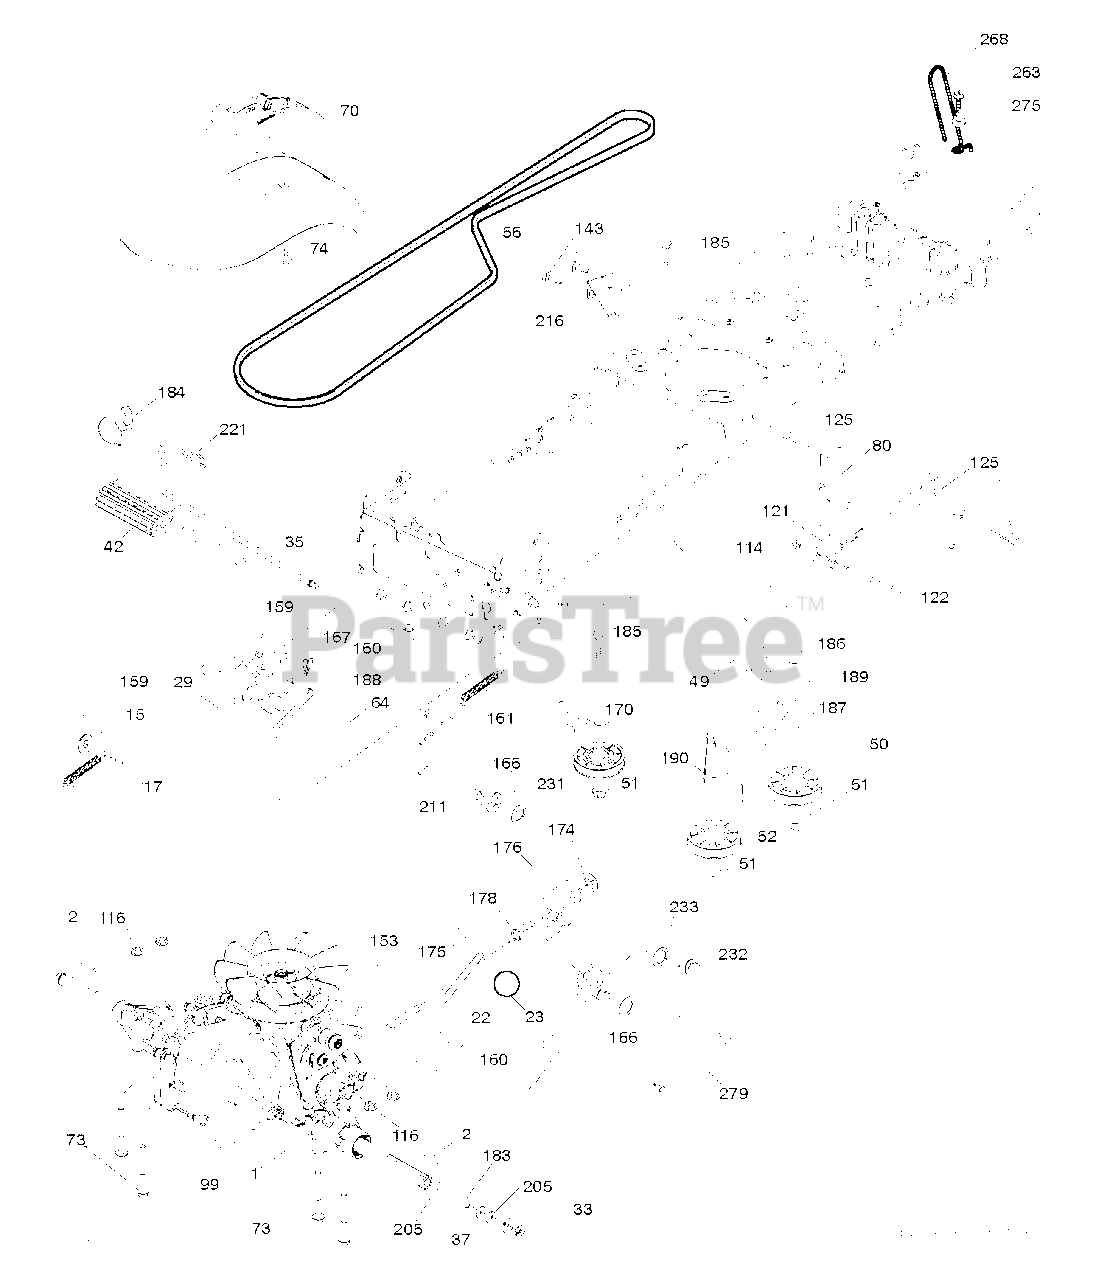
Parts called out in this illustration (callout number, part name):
2	SQUARE KEY
17	SPRING.BRAKE.HG3000/3500
22	ROD.SHIFT.FENDER.TLT.2006
23	KNOB.DUCKHEAD.1/2
29	ROD.BRAKE.T2.TEX
33	E-RING LT
35	ROD, BRAKE, PARK
42	PEDAL COVER T
49	BOLT
50	IDLER.FLAT.910.OFFSET
51	NUT LOCK FLG 3/8-16 UNC
52	IDLER.V-GROOVE.910.OFFSET
56	Ground Drive Belt, T2 HP CE
64	SHAFT.ASM.PEDAL.BRAKE.
70	CONSOLE.SHIFT.STL.HYD.BLACK
73	BOLT HEX 5/16-18 GR 5
74	SCREW.HI-LO.CONSOLE
80	Strap.Torque.T2
99	ROD.ASM.BYPASS.SPRING.T2.FS
114	NUT.71038.31-18.HEX.NYLOCK
116	NUT LOCK HEX FLANGE 5/16-18
121	BRACKET STRAP TORQUE
122	BOLT.5/16-18X2.5
125	SCREW
153	RETAINER M
159	COTTER PIN
160	RETAINER CLIP
161	SPRING, RETURN LT
166	NUT.PUSH.625
167	LATCH.BRAKE.SPRING
170	KEEPER.CENTER SPAN.1.688
174	NUT.PUSH.500.2006
175	SHAFT.ASM.SHFT.T2.TLT
176	ARM.CLEVIS.ROD.SHIFT
178	SPRING.SHIFT.GT2006
183	SPACER, AXLE PVST
184	HANDLE.PARKG.BRK.HUSQ/PRED.667
186	SPACER.RETAINER
187	WASHER 12/32X2X10GA
188	LINK.CLUTCH.GROUND.DRIVE
189	BELLCRANK.GROUND.DRIVE.TEX.
190	KEEPER.BELLCRANK.DRIVE
211	BUSHING.SHAFT.BRAKE.HAND
216	BRACKET.PULLEY.IDLER.W/TEX
221	RETAINER.SPRING.CLIP.H
231	IDLER.V-GROOVE.1.688.OFFSET
232	BOLT FIN HEX 7/16-14 X 1
233	WASHER SERRATED
263	SCREW, 3/8-16X3/4
275	WASHER
279	LINK.SHIFT.T2
